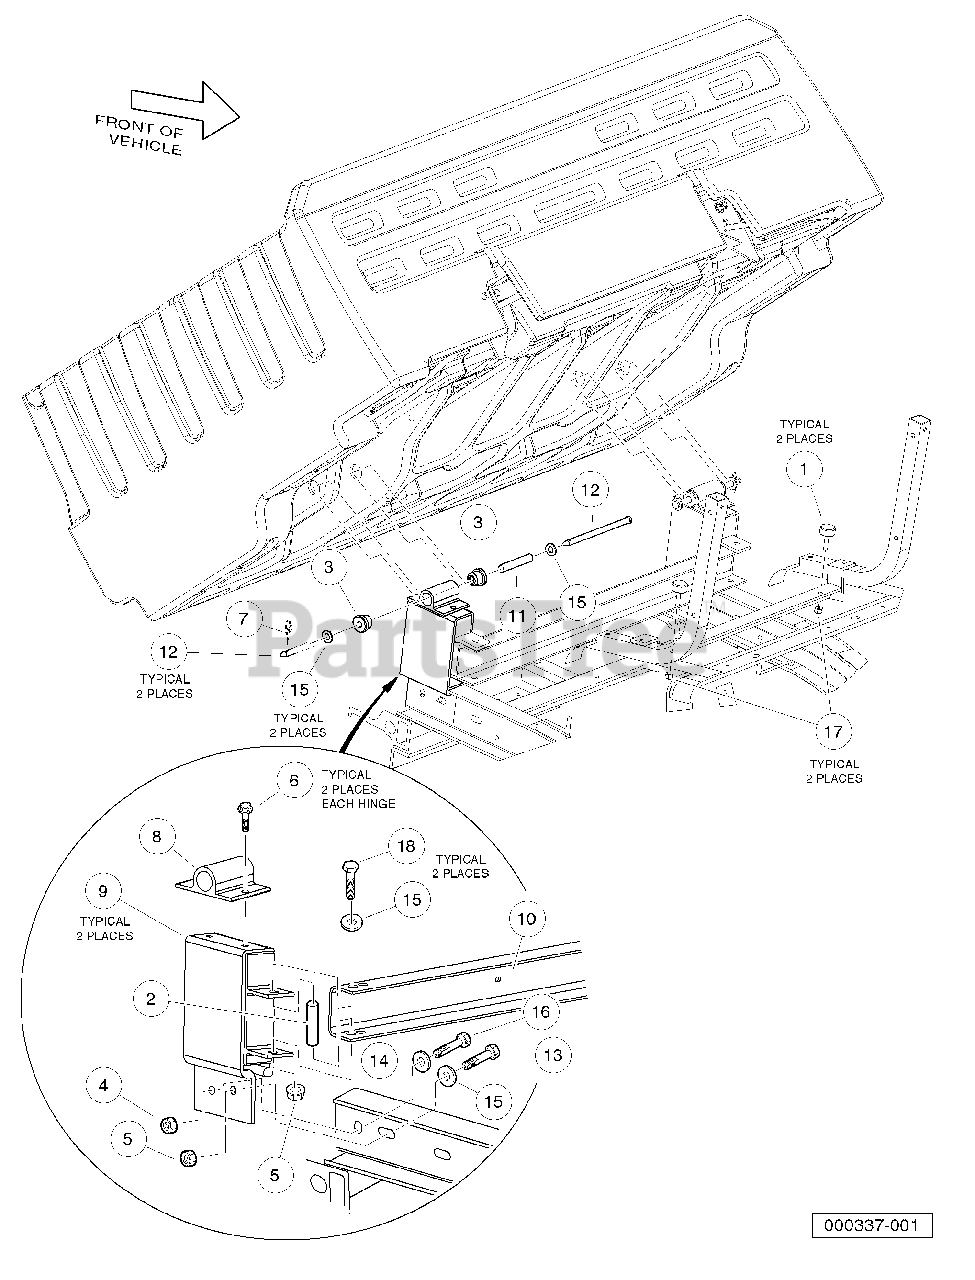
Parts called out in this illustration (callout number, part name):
1	Bumper, Rubber
2	Bushing, Steel
3	Bushing, Urethane
4	Locknut, 1/4-20 Hex Whiz
5	Locknut, 3/8-16 Flanged Dimple
6	Screw, M8X1.25X30, Hex
7	Rue Ring - 1/2
8	Hinge, Roto Bed
9	Support, Hinge
10	Stiffener, Bed Support
11	Bushing, Steel
12	Pin, Clevis, 3/8
13	Screw, 3/8-16 X 1.00 Hex-Head Cap
14	Washer, 1/4 Type A Narrow Flat
15	Washer, 3/8 Type A Flat
16	Screw, 1/4-20 X 0.75 Hex-Head Cap
17	Locknut, 1/4-20 Nylon Insert
18	Screw, 3/8-16 X 3.375 Hex Cap
